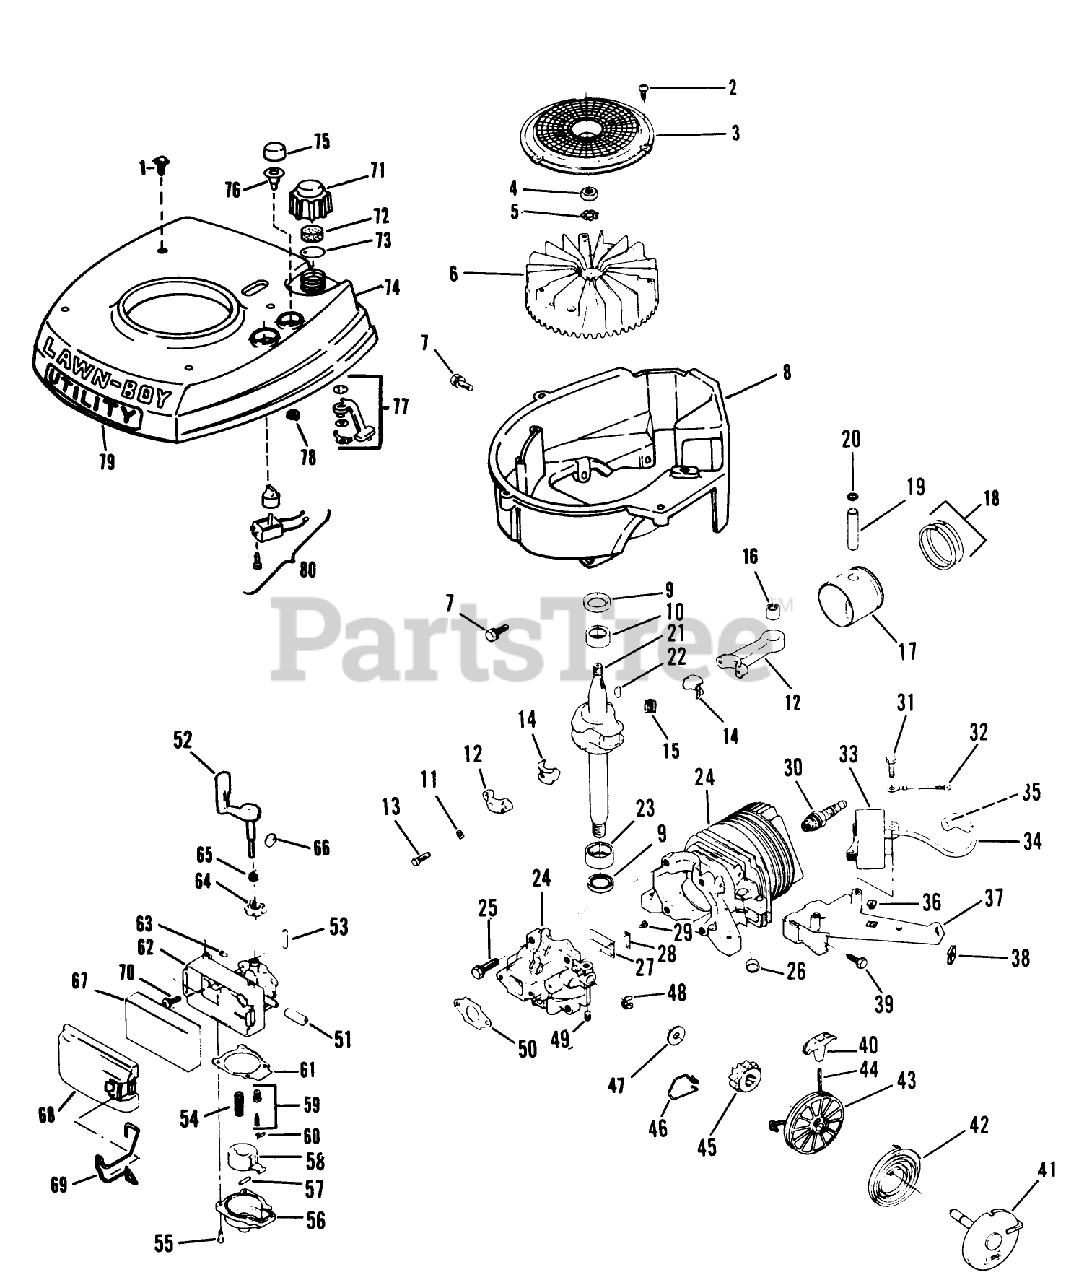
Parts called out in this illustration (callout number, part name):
1	SCREW S
7	Screw
8	SHRD BASE & EYELET
10	BEARING V
13	SCREW
14	LINER ASM
16	BEARING AY F
20	RING-RETAINING
22	KEY
23	BEARING V
25	SCREW S
26	PLUG-CORE VF
28	PLATE-BACKUP, REED
34	HT LEAD&COVER XEV
36	NUT-CLIP
42	SPRING S
43	Pulley
46	SPRING F
47	WASHER S
49	SET SCREW
51	GAS LINE
52	AIR VANE&SHAFT S
53	TUBING PRIMER S
55	SCREW-HH
63	F-SCREW CARB
64	COLLAR-ADJUST, AIRVANE
65	SPRING-THRO. S
66	DISC S
69	RETAINER-COVER, FILTER
70	SCREW
72	BAFFLE - FOAM SM
73	GASKET S
75	P-BULB LAV-RUB
78	LOCKNUT S
